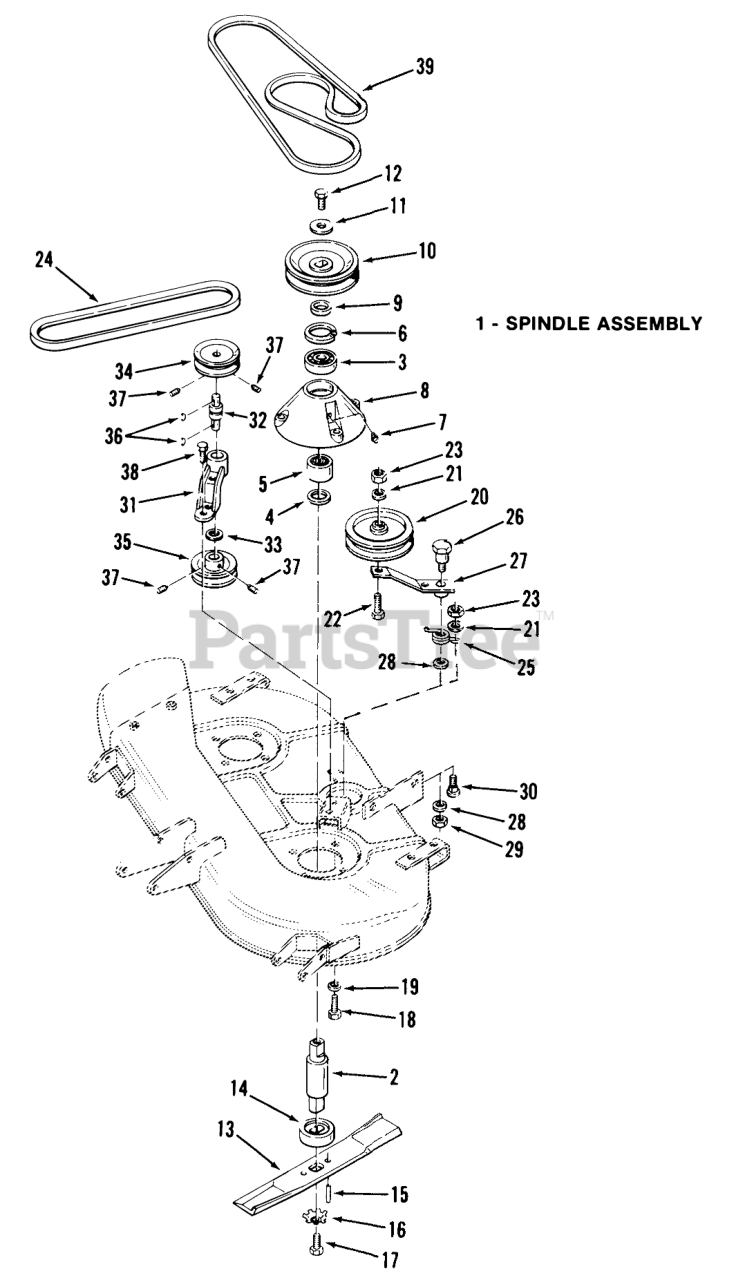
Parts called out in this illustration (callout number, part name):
1	Spindle Assembly (includes parts 2, 3, 4, 5, 6, 7, & 8)
2	SPINDLE MOWER
3	BEARING-BALL
4	OIL SEAL
5	BEARING-NEEDLE
6	INT SNAP RING
7	Fitting-Grease
8	HOUSING
9	SPACER
10	PULLEY-BLADE
11	WASHER
12	Bolt
13	S/A BLADE KIT
14	Spindle Cup
15	SPIROL ROLL PIN
16	WASHER
17	Bolt
18	Bolt
19	LOCKWASHER
20	Idler Pulley
21	Washer
22	BOLT
23	Nut
24	V-BELT
25	SPRING-TORSION
26	BOLT-SHOULDER
27	Idler Arm
28	WASHER
29	Hex Nut 7/16-14
30	Bolt
31	HOUSING DRIVE BRG R
32	BEARING-INT SHAFT
33	Snap Ring
34	PULLEY
35	Pulley
36	KEY-WOODRUFF
37	Set Screw
38	Bolt
39	V-BELT
